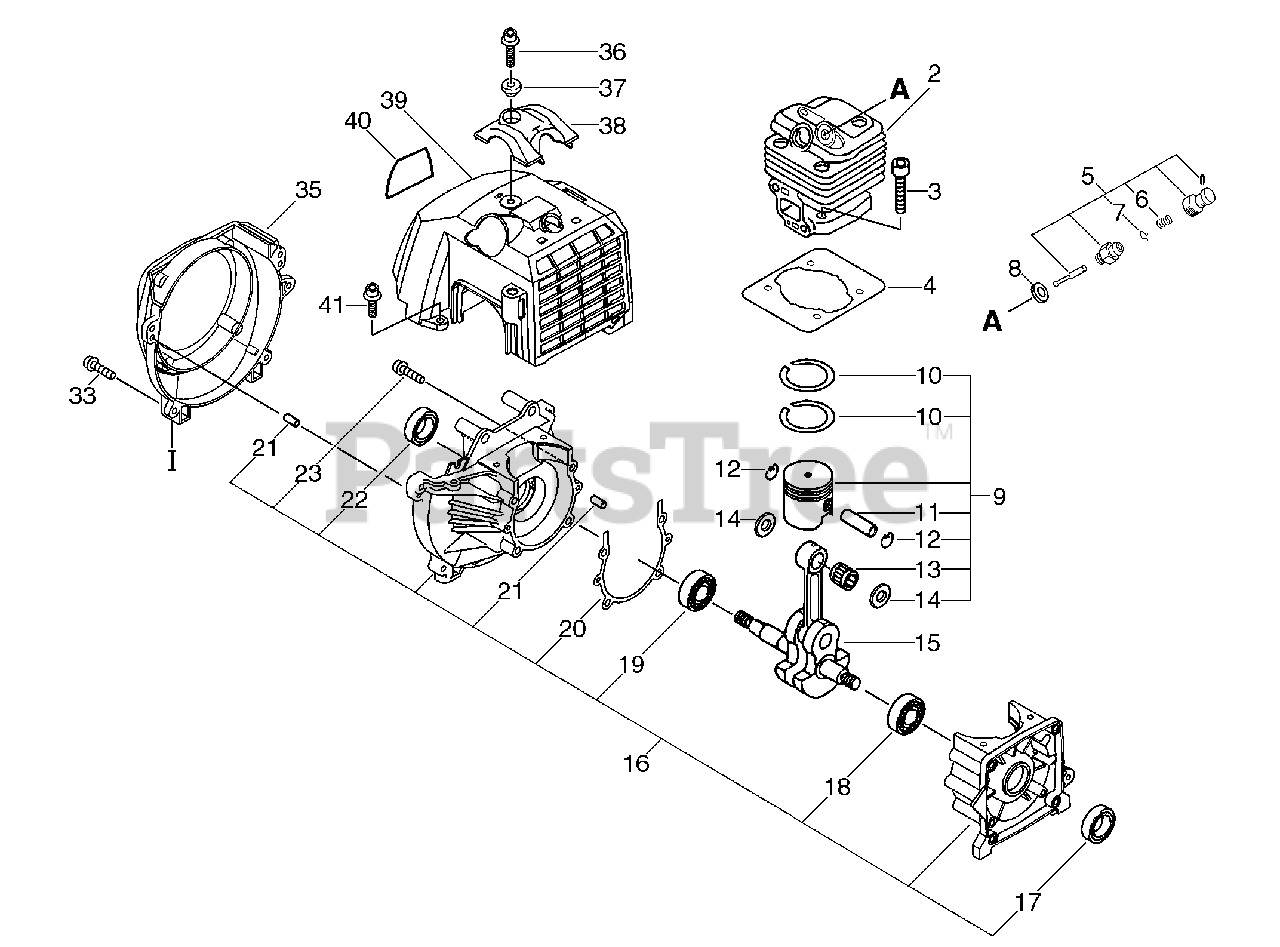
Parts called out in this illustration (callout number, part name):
2	CYLINDER
3	BOLT 5×20
4	GASKET, CYLINDER
5	VALVE, DECOMPRESSION
8	GASKET
9	PISTON KIT
10	RING, PISTON
11	PIN, PISTON 10
12	RING, SNAP 8
13	BEARING, NEEDLE 10
14	WASHER, THRUST
15	CRANKSHAFT ASSY
16	CRANKCASE KIT
17	SEAL, OIL 12
18	BEARING, BALL 6203 C3
19	BEARING, BALL - 6201 C3
20	GASKET, CRANKCASE
21	PIN, LOCATING 4×8
22	SEAL, OIL
23	BOLT M5×35
33	BOLT 5×20
35	COVER, FAN
36	BOLT 5×20
37	COLLAR 5
38	GUARD, TOP
39	COVER, ENGINE
40	LABEL, MODEL
41	BOLT 5×12
